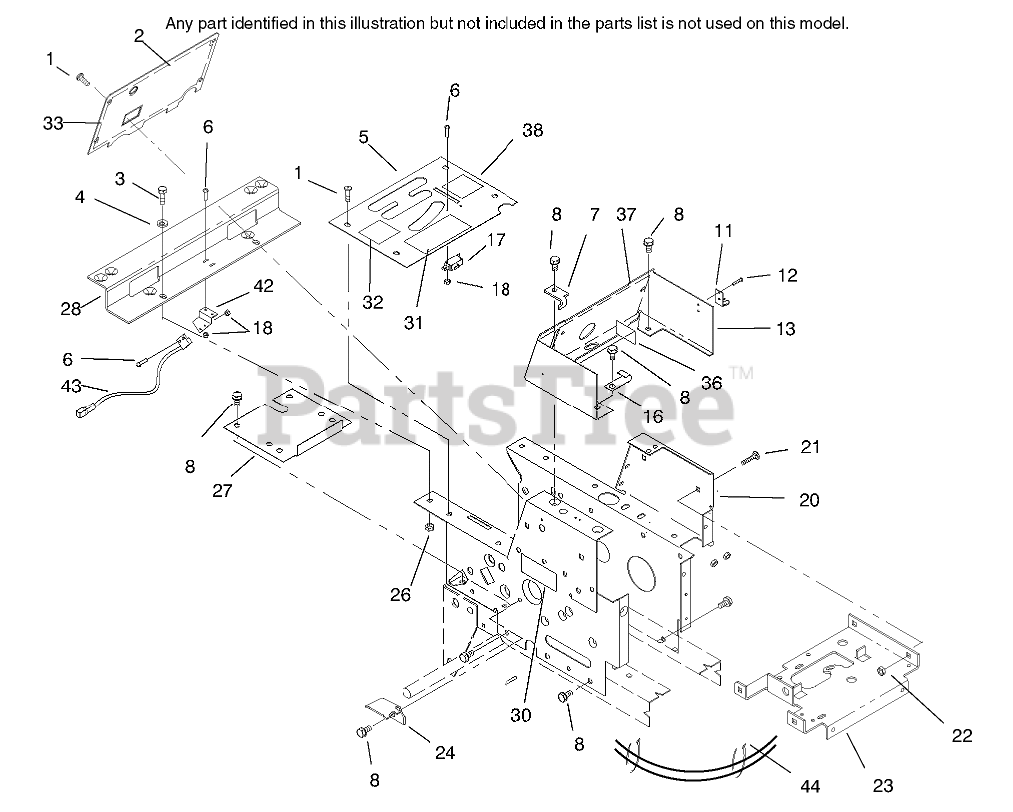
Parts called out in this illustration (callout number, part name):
1	SCREW-PPH
2	PLATE-HOODSTAND
3	SCREW-HH
4	WASHER-PLAIN
5	Plate-Shift
6	SCREW-PPH
7	STOP-PTO
8	Bolt
11	KEEPER-LATCH
12	RIVET-POP
13	Console
16	J-CLIP
17	SWITCH
18	NUT-HEX
20	HOODSTAND ASM
21	BOLT CARR. 5/16X1/2 BK
22	Nut
23	SUPPORT-BATTERY
24	BRACKET-BELT SUPPORT
26	NUT-LOCK, NI
27	COVER-DUST
28	BRACKET-FENDER
30	DECAL - MODEL 312-8
31	DECAL-DANGER
32	DECAL-SHIFT PATTERN
33	DECAL - DASH, LOWER
36	DECAL ELECT SYSTEM
37	DECAL - CONSOLE
38	DECAL-PARKING, BRAKE
39	RELAY
40	SCREW-HHF
41	NUT-LOCK, NI
42	Bracket-Switch
43	SWITCH-REED, MAGNETIC
44	TIE-CABLE
